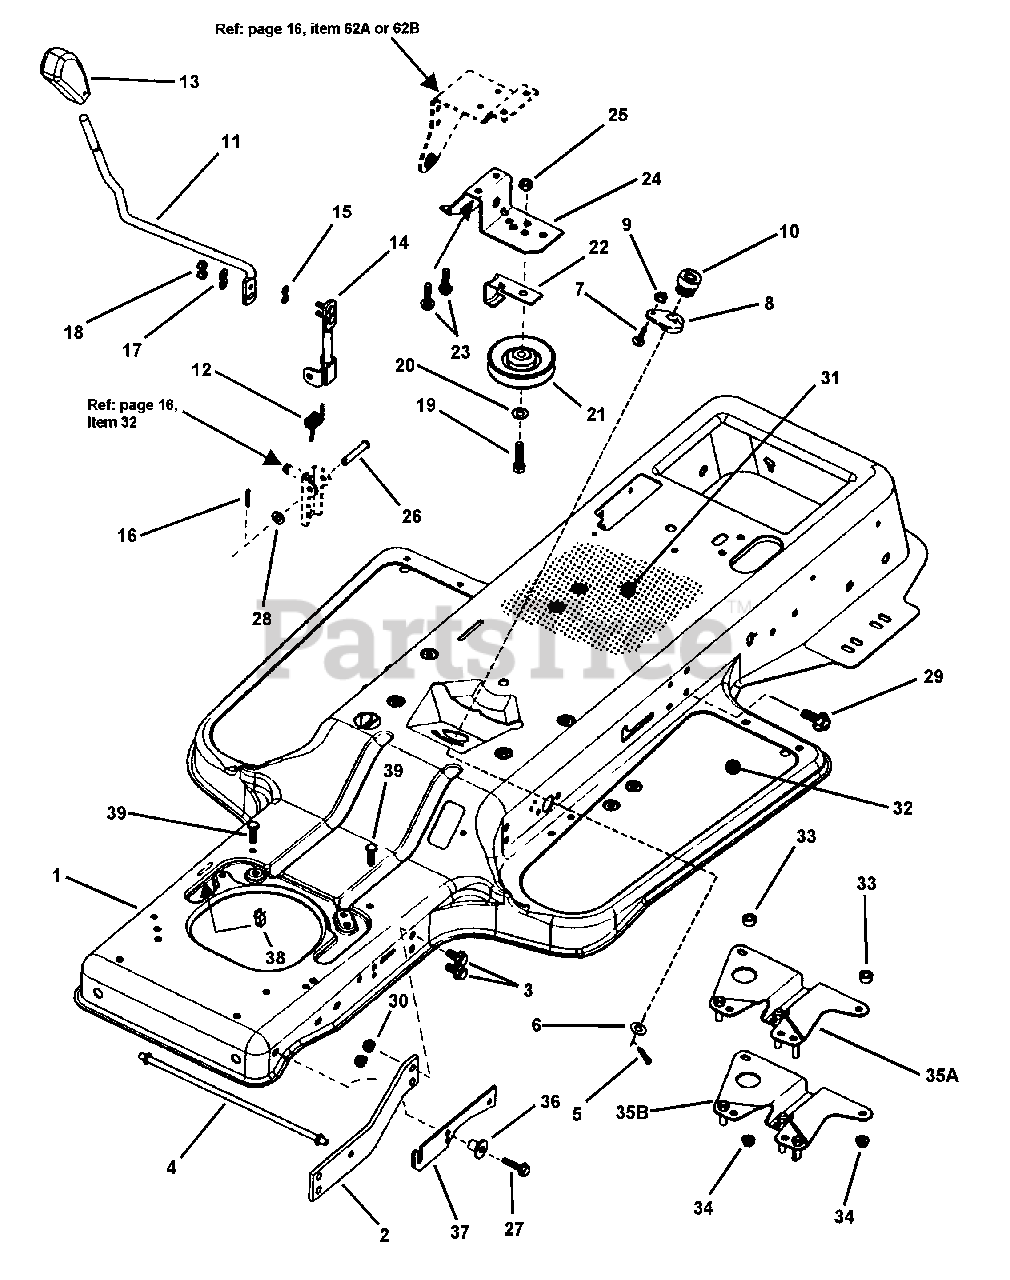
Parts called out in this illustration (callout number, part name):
1	FRAME, Tractor (1 Piece)
2	BRACE, Frame- 48"
3	BOLT, 3/8-16 x 3/4" Hex Flange Lock
4	GUIDE, Belt- 48"
5	COTTER-PIN, 1/8 x 3/4"
6	WASHER, 1/2 Shim
7	BOLT, 1/4-20 x 5/8" Short Neck Carriage, Grade 5
8	ASSEMBLY, Steering Adjuster
9	NUT, 1/4-20 Hex Flange Lock, Grade 5
10	GEAR, Steering Pinion
11	LEVER, Shift (Upper)
12	SPRING, Shift Torsion Shift Lever
13	KNOB, Deck Lift Lever
14	WELDMENT, Shift Lever (Upper)
15	WASHER, 1/4 Internal Tooth Lock
16	COTTER-PIN, 5/32 x 1"
17	WASHER, 1/4 Flat
18	NUT, 1/4-20 Hex Nyloc
19	SCREW, 3/8-16 x 1-1/2" Hex Head Cap, Grade 5
20	WASHER, 3/8" Flat
21	PULLEY, Idler
22	GUIDE, Pulley Belt
23	SCREW, 5/16-18 x 1-1/4" Swage
24	SUPPORT, PTO Lever
25	NUT, 3/8-16 Hex Center Lock, Grade 5
26	PIN, 5/16 x 1.73" Clevis
27	SCREW, 5/16-18 x 1-1/4" Self-Tapping
28	WASHER, 5/16" Flat
29	SCREW, 5/16-18 x 5/8" Hex Washer Self-Tap
30	NUT, 3/8-16 Hex Flange Lock
31	DECAL, Instruction Frame Top (EC)
32	PAD, Foot (Rubber Deluxe)
33	SPACER, 11/32 x 5/8 x 5/16"
34	NUT, 5/16-18 Hex Flange Lock, Grade 5
35A	ASSEMBLY, Anti-Spin/Belt Guide
35B	ASSEMBLY, Anti-Spin/Belt Guide
36	BUSHING, Flange
37	BRACKET, Hood Pivot
38	CLIP, Wire
39	SCREW, 5/16-18 x 1" Hex Head Cap, Grade 2
62A	BRACKET, Rear lift/PTO Lever
62B	BRACKET, Rear lift/PTO Lever
